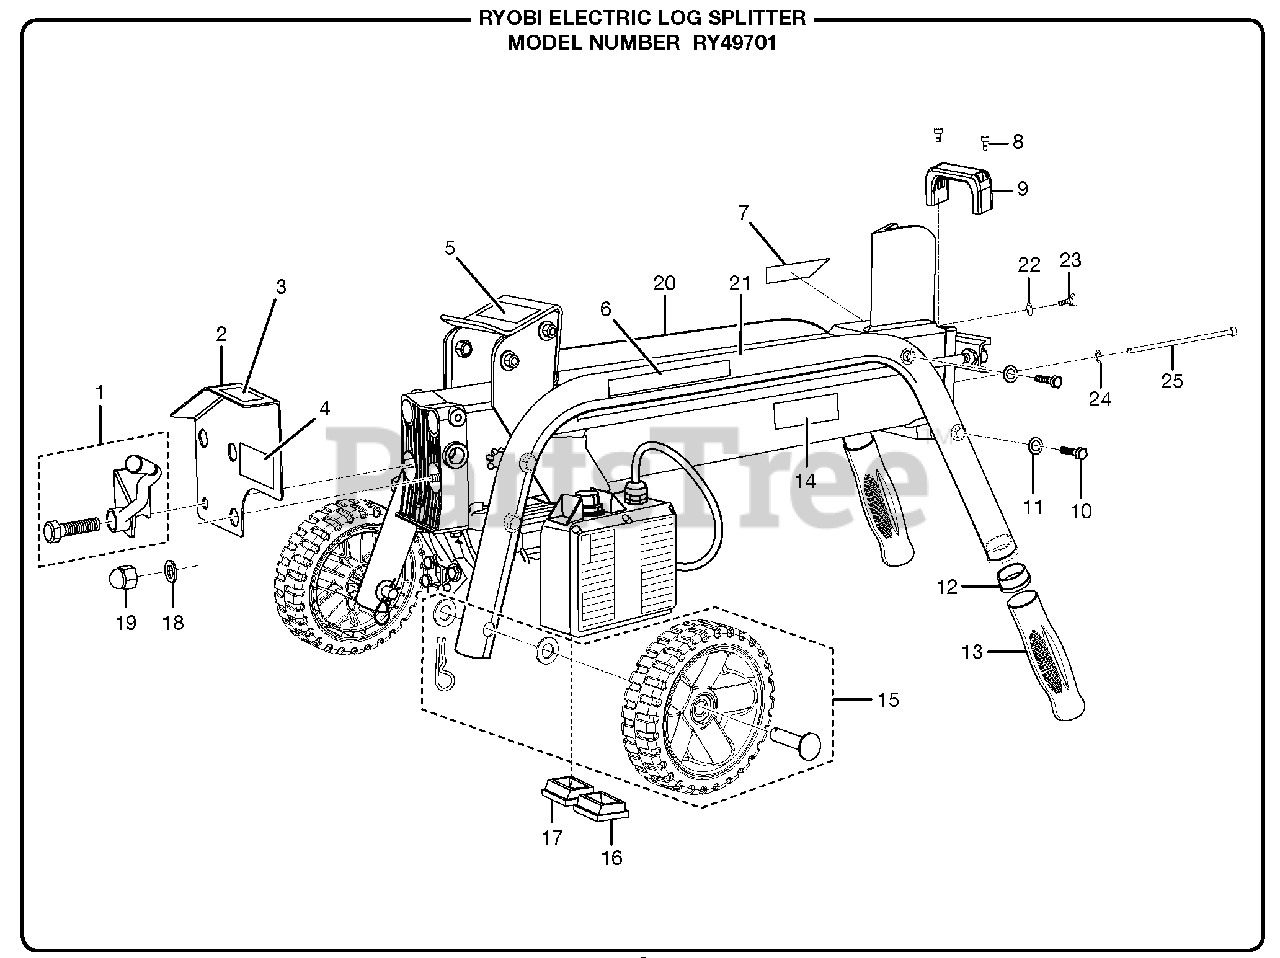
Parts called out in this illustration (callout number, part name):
1	HYDRAULIC CONTROL LEVER
2	CONTROL LEVER GUARD
3	WARNING LABEL
5	BLEED SCREW INSTRUCTION LABEL
6	WARNING LABEL
7	BLEED SCREW LABEL
8	SCREW (M5 X 16 mm)
10	BOLT (M8 X 55 mm)
13	RUBBER GRIP
15	WHEEL ASSEMBLY
16	RUBBER FOOT (R)
17	RUBBER FOOT (L)
20	LEG FRAME (R)
21	LEG FRAME (L)
